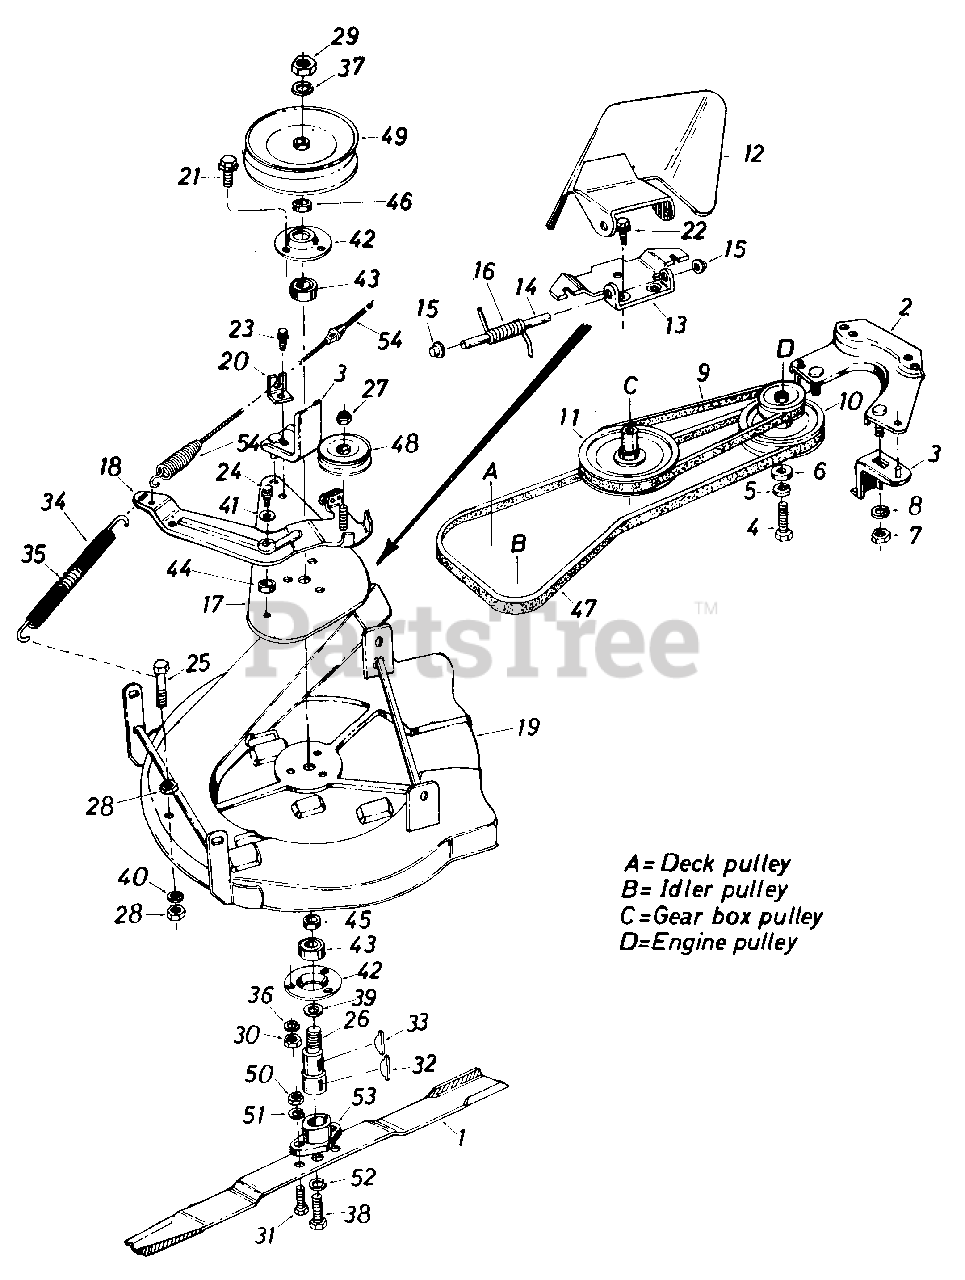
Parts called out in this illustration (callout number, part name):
1	26" Blade
2	Belt Guard Cup Ass'y.
3	Belt Keeper Ass'y.
4	Hex Bolt 3/8-24 x 1.00" Lg.
5	L-Wash. 3/8" I.D.
6	Fl-Wash. .406" I.D. x 1.25" O.D.
7	Hex Nut 5/16-18 Thd.
8	L-Wash. 5/16" I.D.
9	3V-Belt 28" Lg.
10	Double Pulley
11	3/8" V-Pulley .502" I.D. x 6.5" O.D.
12	Chute Cover Ass'y. Comp.
13	Adapter Plate
14	Hinge Pin
15	Cap Speed Nut 1/4" Rod
16	Torsion Spring
17	Deck Belt Guard Plate
18	Deck Idler Brkt. Ass'y.
19	26" Deck Ass'y.
20	Cable Support Brkt.
21	Hex Sems Bolt 5/16-18 x 1.00" Lg.
22	Hex Wash. S-Tap Scr. 1/4-20 x .50" Lg.
23	Hex Wash. Hd. B-Tap Scr. 5/16-18 x .50" Lg.
24	Hex L-Bolt 5/16-18 x 1.00" Lg
25	Hex Bolt 1/4-28 x 1.50" Lg.
26	Blade Spindle
27	Hex Ins. L-Nut 3/8-24 Thd.
28	Hex Cent. L-Nut 1/4-28 Thd.
29	Hex Jam Nut 5/8-11 Thd.
30	Hex Nut 5/16-18 Thd.
31	Hex Bolt 5/16-24 x 1.00" Lg. (Grade 5)
32	#6 Hi-Pro Key 5/32 x 5/8" Dia.
33	#61 Hi-Pro Key 3/16" x 5/8" Dia.
34	Plastic Tube .52" I.D. x 7.0" Lg.
35	Ext. Spring .50" O.D. x 5.2" Lg.
36	L-Wash. 5/16" I.D.
37	L-Wash. 5/8" I.D.
38	Hex Bolt 3/8-24 x 1.50" Lg. (Grade 5)
39	Bearing Shield
40	L-Wash. 1/4" I.D.
41	Fl-Wash. .330" I.D. x 1.25" O.D. x .120
42	Bearing Housing
43	Ball Brg. .787" I.D. x 1.85" O.D.
44	Spacer .315" I.D. x .75" O.D. x .37" Lg.
45	Spacer .836" I.D. x 1.01" O.D. x .320" Lg.
46	Spacer .630" I.D. x 1.135" O.D. x .195" Lg.
47	"V"-Belt-A Sec. x 59.0" Lg.
48	"V"-Idler 3.06" O.D.
49	5/8" V-Pulley .625" I.D. x 7.0" O.D.
50	Hex Nut 5/16-24 Thd.
51	L-Wash. 5/16" I.D.
52	L-Wash. 3/8" I.D. - Heavy Duty
53	Blade Adapter Kit
54	Clutch Cable - 56.0"
